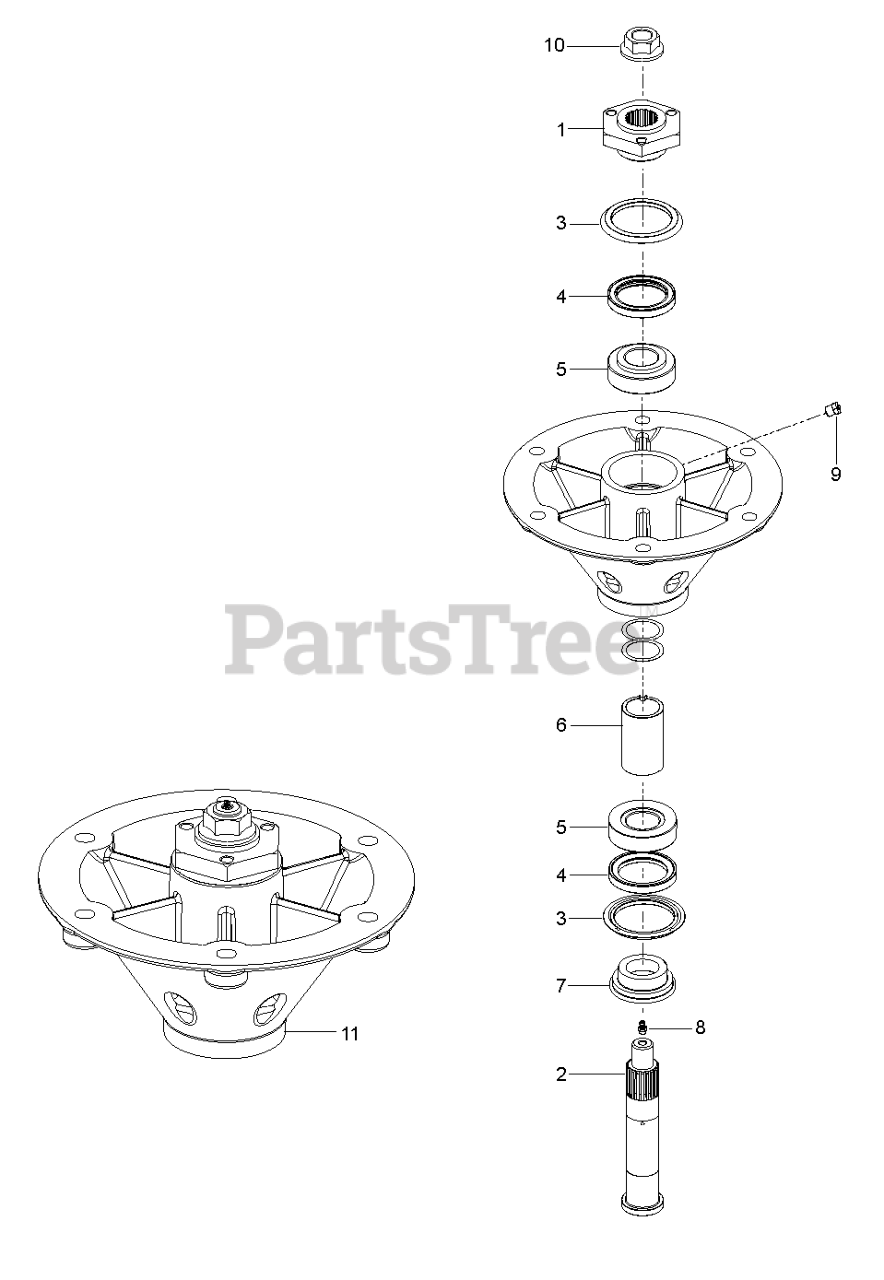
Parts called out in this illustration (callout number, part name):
3	SEAL V-RING 55MM
4	SEAL SHAFT
5	BEARING KIT
8	ZERK
9	PLUG-VENTED
10	NUT FLANGE 3/4-16
11	SPINDLE.ASSY.IRON
